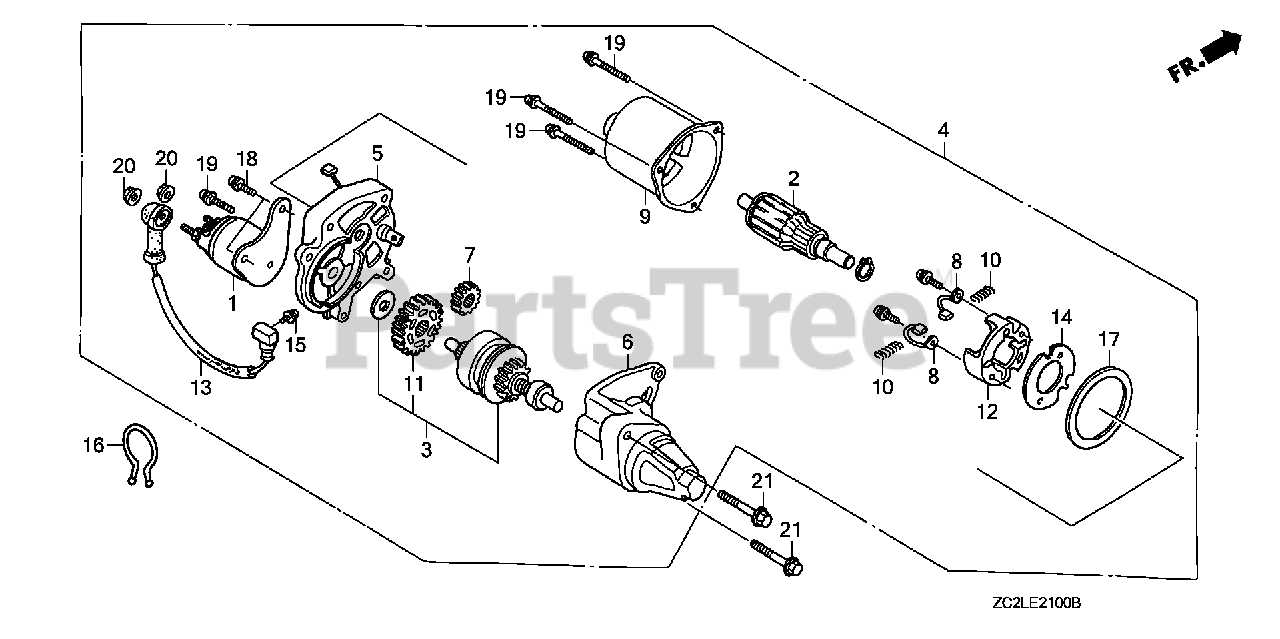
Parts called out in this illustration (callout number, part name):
1	CONTACTOR ASSY.
3	CLUTCH, OVERRUNNING
4	STARTER MOTOR UNIT
5	BRACKET, CENTER
6	BRACKET, FR.
7	GEAR, DRIVE PINION
10	SPRING, BRUSH RETURN
11	GEAR, REDUCTION
12	HOLDER, BRUSH
13	WIRE, WATER COVER
15	SCREW-WASHER (4X6)
16	CLIP, PURSE LOCK
18	BOLT-WASHER (5X14)
19	SCREW-WASHER (5X32)
20	NUT-WASHER (6MM)
21	BOLT, FLANGE (8X35)
